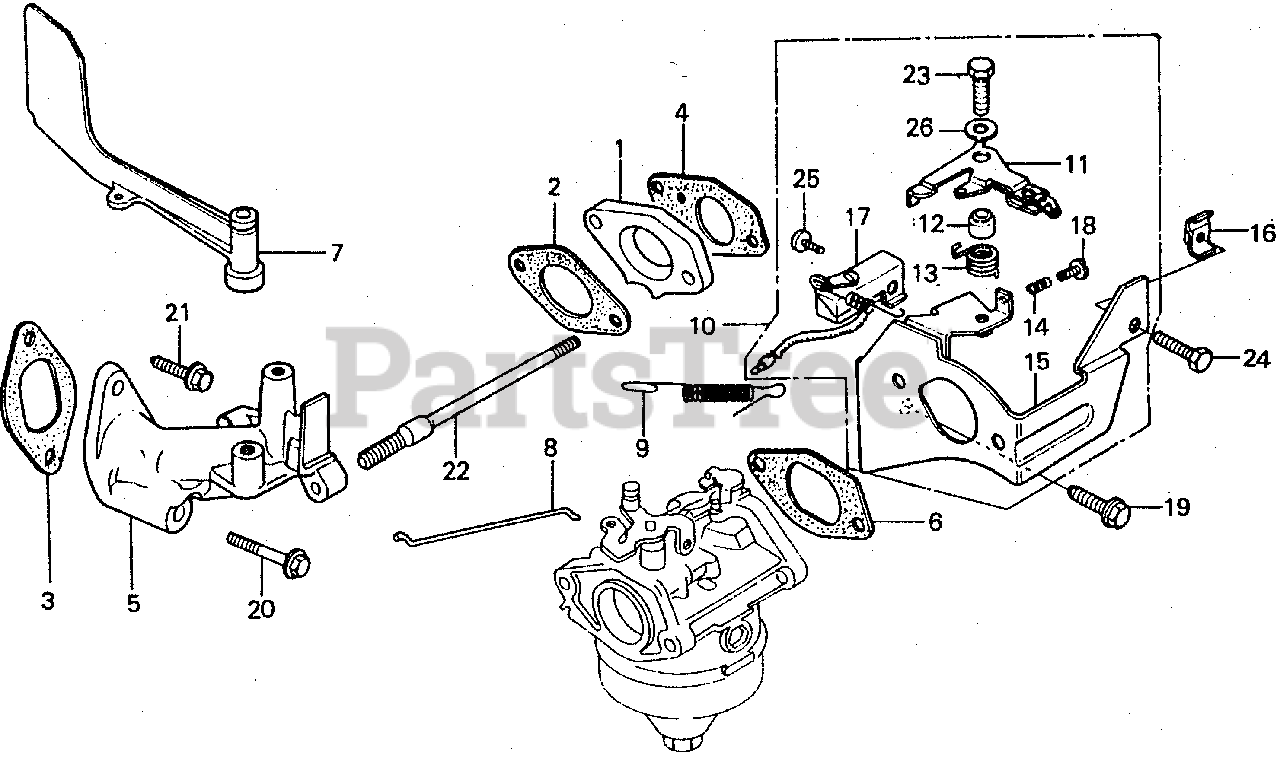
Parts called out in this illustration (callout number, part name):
1	INSULATOR, CARBURETOR
2	GASKET, INSULATOR
3	GASKET, MANIFOLD (NOT AVAILABLE)
4	GASKET, CARBURETOR
5	MANIFOLD, IN. (NOT AVAILABLE)
6	GASKET, AIR CLEANER
7	FLUTTER, GOVERNOR (NOT AVAILABLE)
8	ROD, GOVERNOR (NOT AVAILABLE)
9	SPRING, GOVERNOR
10	CONTROL ASSY.
11	LEVER, CONTROL
12	COLLAR, LEVER SETTING
13	SPRING, RETURN
14	SPRING, STOPPER LEVER
15	STAY, CLEANER CASE
16	HOLDER, WIRE
17	SWITCH ASSY., ENGINE STOP
18	BOLT (4X20) (NOT AVAILABLE)
19	BOLT, FLANGE (6X12) (CT200)
20	BOLT, FLANGE (6X50)
21	BOLT, FLANGE (6X20) (CT200)
22	BOLT, STUD (6X141) (NOT AVAILABLE)
23	BOLT, HEX. (5X20)
24	BOLT, HEX. (6X14)
25	SCREW, PAN (4X8)
26	WASHER, PLAIN (5MM)
